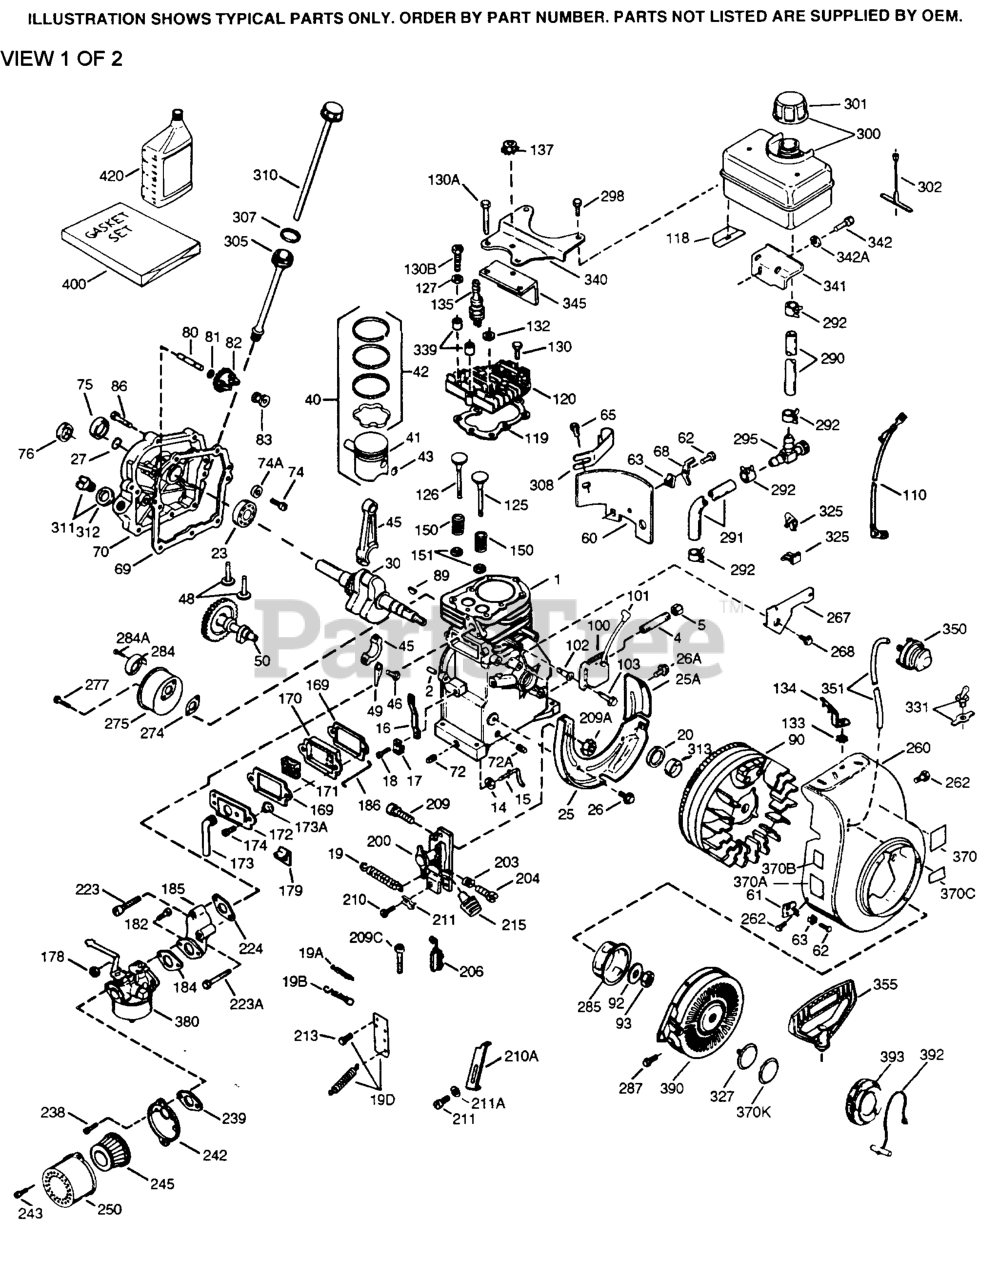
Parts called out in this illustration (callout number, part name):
1	CYLINDER
2	DOWEL PIN
15	GOVERNOR ROD
16	LINK & LEVER
18	SCREW
19	EXT SPRING
20	OIL SEAL
25A	EXTENSION
30	CRANKSHAFT
40	PISTON ASSY 020
40	PISTON ASSY 010
40	PISTON ASSY STD
41	PISTON & PIN 10
41	PISTON & PIN ST
41	PISTON & PIN 20
42	RING SET STD
42	RING SET 020
42	RING SET 010
43	RET RING
45	CONN ROD
48	VALVE LIFTER
49	OIL DIPPER
50	CAMSHAFT
60	EXTENSION
70	CYL COVER
72	PIPE PLUG
75	OIL SEAL
80	GOV SHAFT
83	GOV SPOOL
90	FLYWHEEL
100	LAMINATION
101	PLUG COVER
102	STUD
110	GROUND WIRE
120	CYL HEAD
125	EXH VALVE STD
125	EXH VALVE OS
126	EX/INT VALVE OS
126	INT VALVE ST
135	SPARK PLUG
150	VALVE SPRING
151	VALVE CAP
170	BREATHER
171	ELEMENT
173A	GROMMET
185	INTAKE PIPE
186	LINK & LEVER
200	CONTROL ASSY
203	COMP SPRING
204	SCREW
206	TERMINAL
242	BRACKET
243	SCREW
245	AIR CLEANER
250	CLEANER BODY
260	BLOWER HSG
267	BRACKET
275	MUFFLER
285	STARTER CUP
290	FUEL LINE
300	FUEL TANK
301	FUEL CAP
311	FILLER PLUG
327	STARTER PLUG
340	TANK BRACKET
380	CARBURETOR
390	STARTER
400	GASKET SET
